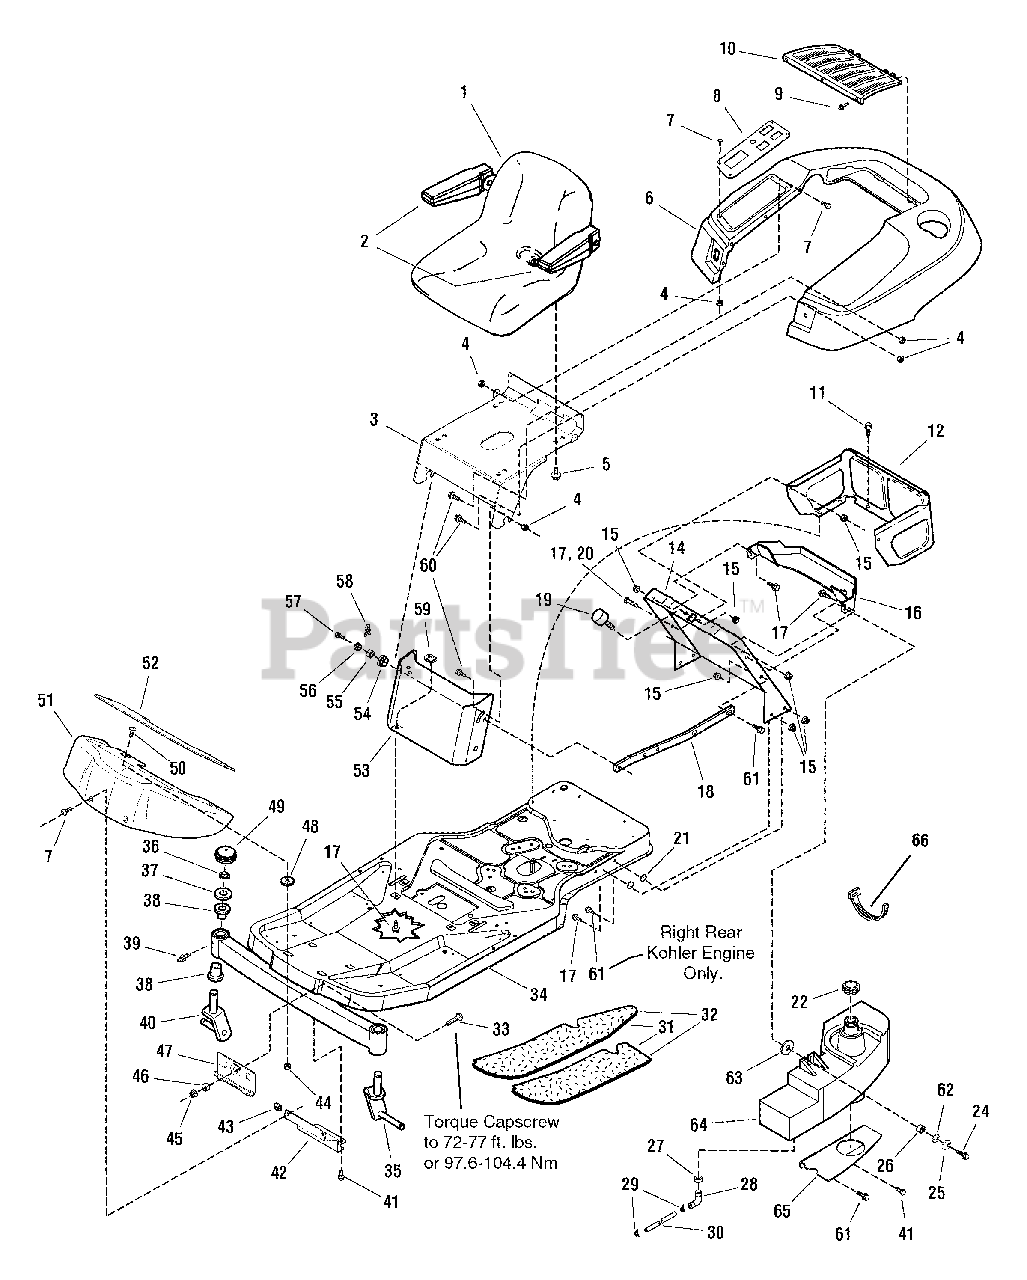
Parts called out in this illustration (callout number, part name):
1	SEAT ASSEMBLY, with Arm Rests
2	ARM REST KIT, (L.H. & R.H.)
3	SUPPORT, Seat
4	NUT, Hex Flange ESNA, 1/4-20
5	CAPSCREW, Hex Head Whiz Lock Dog Point, 5/16-18 x 3/4
6	DECK, Seat
7	SCREW, Truss Head Torx Drive, 1/4-20 x 3/4
8	PLATE, Pod Control
9	RIVET, Pop
10	SCREEN, Seat Deck
11	CAPSCREW, Hex Washer Head Taptite, 1/4-20 x 1/2
12	SHROUD, Rear
14	SUPPORT, Seat Deck
15	NUT, Hex Flange Whiz Lock, 5/16-18
16	DUCT, Air Inlet
17	CAPSCREW, Hex Head Whix Lock, 5/16-18 x 3/4, G5
18	BRACE, Tank
19	BUMPER, Rubber
20	CAPSCREW, Hex Head Whiz Lock, 5/16-18 x 1-1/2, G5
21	NUT, Push
22	CAP, Fuel Tank
24	CAPSCREW, Hex Washer Head Taptite, 5/16-18 x 1-1/2
25	WASHER, 5/16
27	BUSHING, Fuel Tank
28	ELBOW, with Screen, Gas Tank to Fuel Line
29	CLAMP, Hose, Wire Type E
30	HOSE, Fuel 8.5" Long
31	PAD, Footrest, R.H.
32	PAD, Footrest, L.H.
33	CAPSCREW, Hex, 1/2-13 x 1-1/2
34	FRAME & SPINDLES ASSEMBLY
35	ARM, Caster, L.H.
36	RING, E-Retaining
37	WASHER
39	FITTING, Lube
40	ARM, Caster, R.H.
41	SCREW, Hex Washer Head Taptite, 5/16-18 x 3/4
42	BRACKET, Footrest Support
43	NUT, Speed Lug Type, 1/4-20
44	NUT, Hex Flange Whiz Lock, 1/4-20
45	NUT, Hex Flange, Two-Way Lock, 1/2-13
47	HOOK & WASHER ASSEMBLY
48	NUT, Push, 1/4
50	CARRIAGE BOLT, 1/4-20 x 3/4
51	PANEL, Footrest
52	PAD, Footrest, Front
53	PANEL, Front
56	PIVOT, Hood
57	PIN, Quick
58	CAPSCREW, Hex Washer Head Taptite, 5/16-18 x 1
59	NUT, Speed, Lug Type, 5/16-18
60	SCREW, Hex Flange Whiz Lock, 1/4-20 x 5/8
61	CAPSCREW, Hex Flange Whiz Lock, 5/16-18 x 1-1/4, G5
62	LOCKWASHER, External Tooth, 3/8
63	WASHER, 3/8 x 1-1/4 x 1/4
64	TANK, Fuel
65	BRACKET, Fuel Tank
66	TIE, Self-Locking
